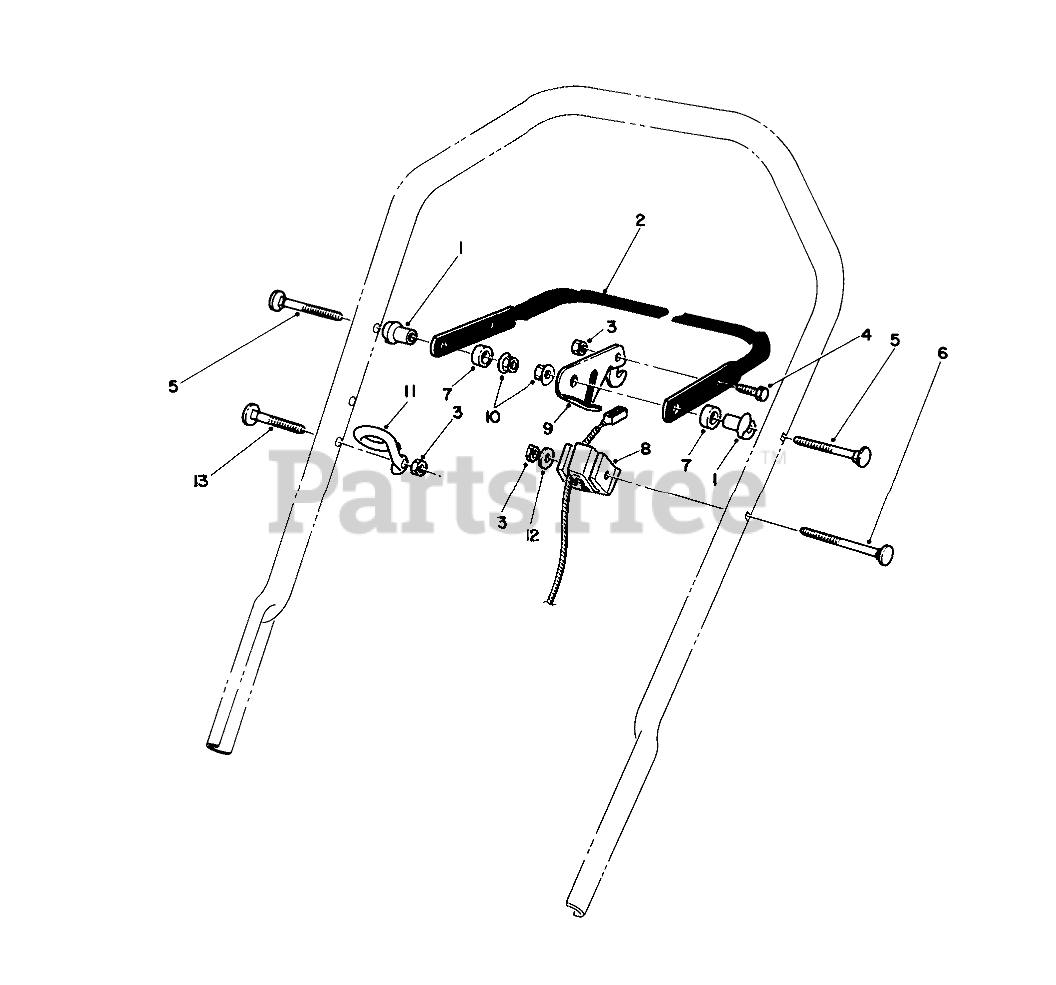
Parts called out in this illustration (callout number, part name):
1	SPACER-SUPPORT
2	Bar-Control
3	NUT-LOCK, NI
4	SCREW-HH
5	5/16-18 X 2 HNDLE SCREW
6	HANDLE SCREW
7	SPACER-NYLON
8	SUPPORT-CABLE
9	LEVER-CONTROL
10	NUT-LOCK, NI
11	Guide
12	WASHER-FLAT
13	HANDLE SCREW
